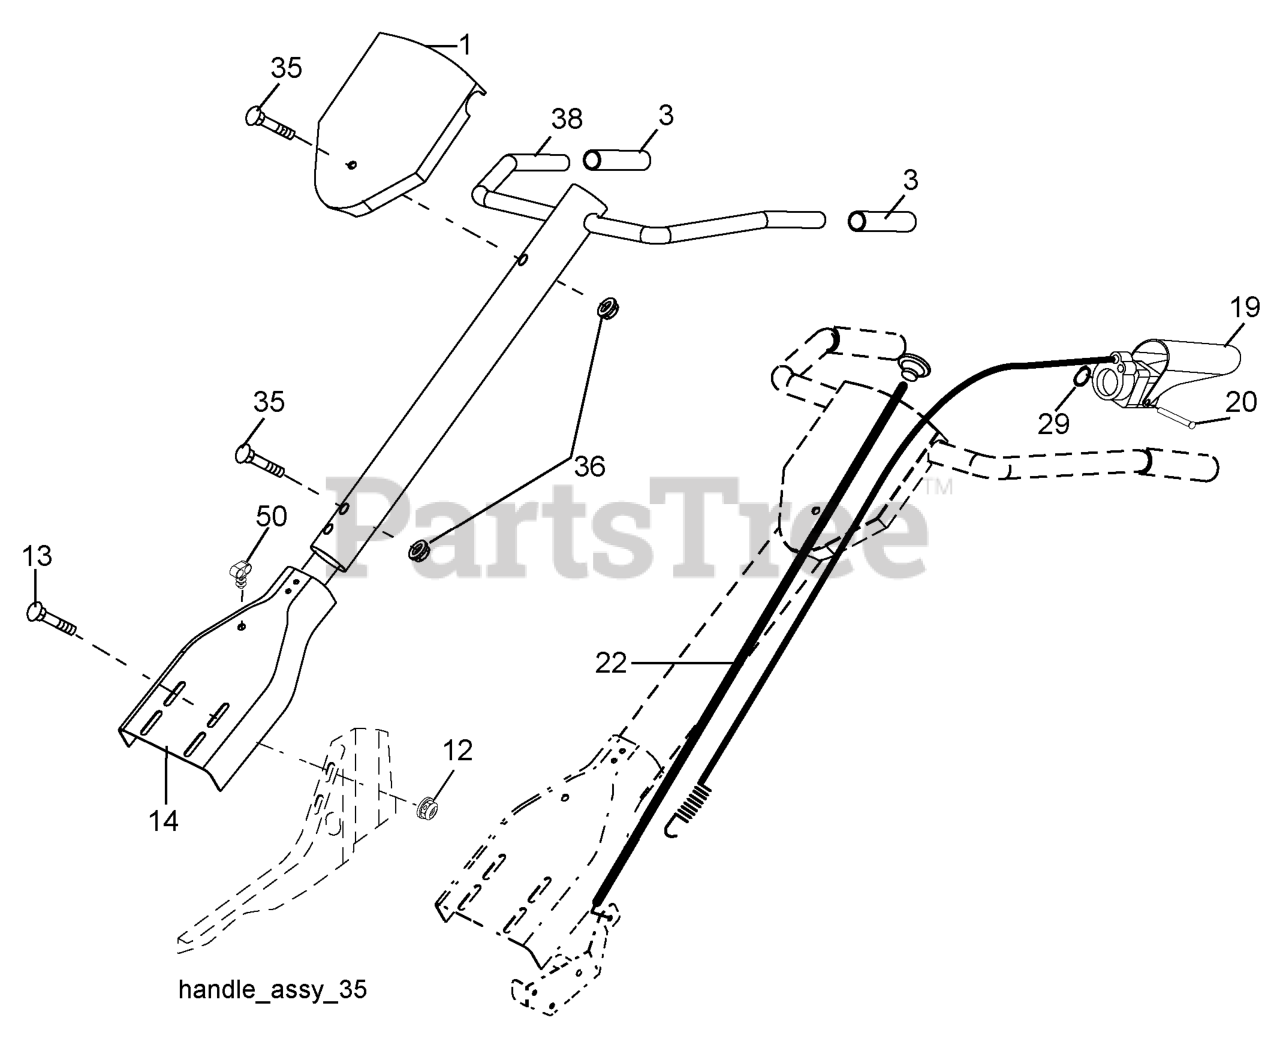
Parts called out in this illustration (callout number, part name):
1	PANEL.PNT.CONTROL.W/REVERSE
3	GRIP.HANDLE.BLACK
12	NUT
13	BOLT.RH.SQNK.5/16
14	PANEL ASM. POLE
19	CONTROL.ASM.TINE
20	PIN, PIVOT
22	CABLE ASM REVERSE
29	RETAINING.RING.#5103-25
35	BOLT.5/16-18X2.5
36	LOCKNUT-FLANGE 5/16-18
38	RP ASSEMBLY, HANDLE COLUMN
50	CLIP.ROUTING DUAL
